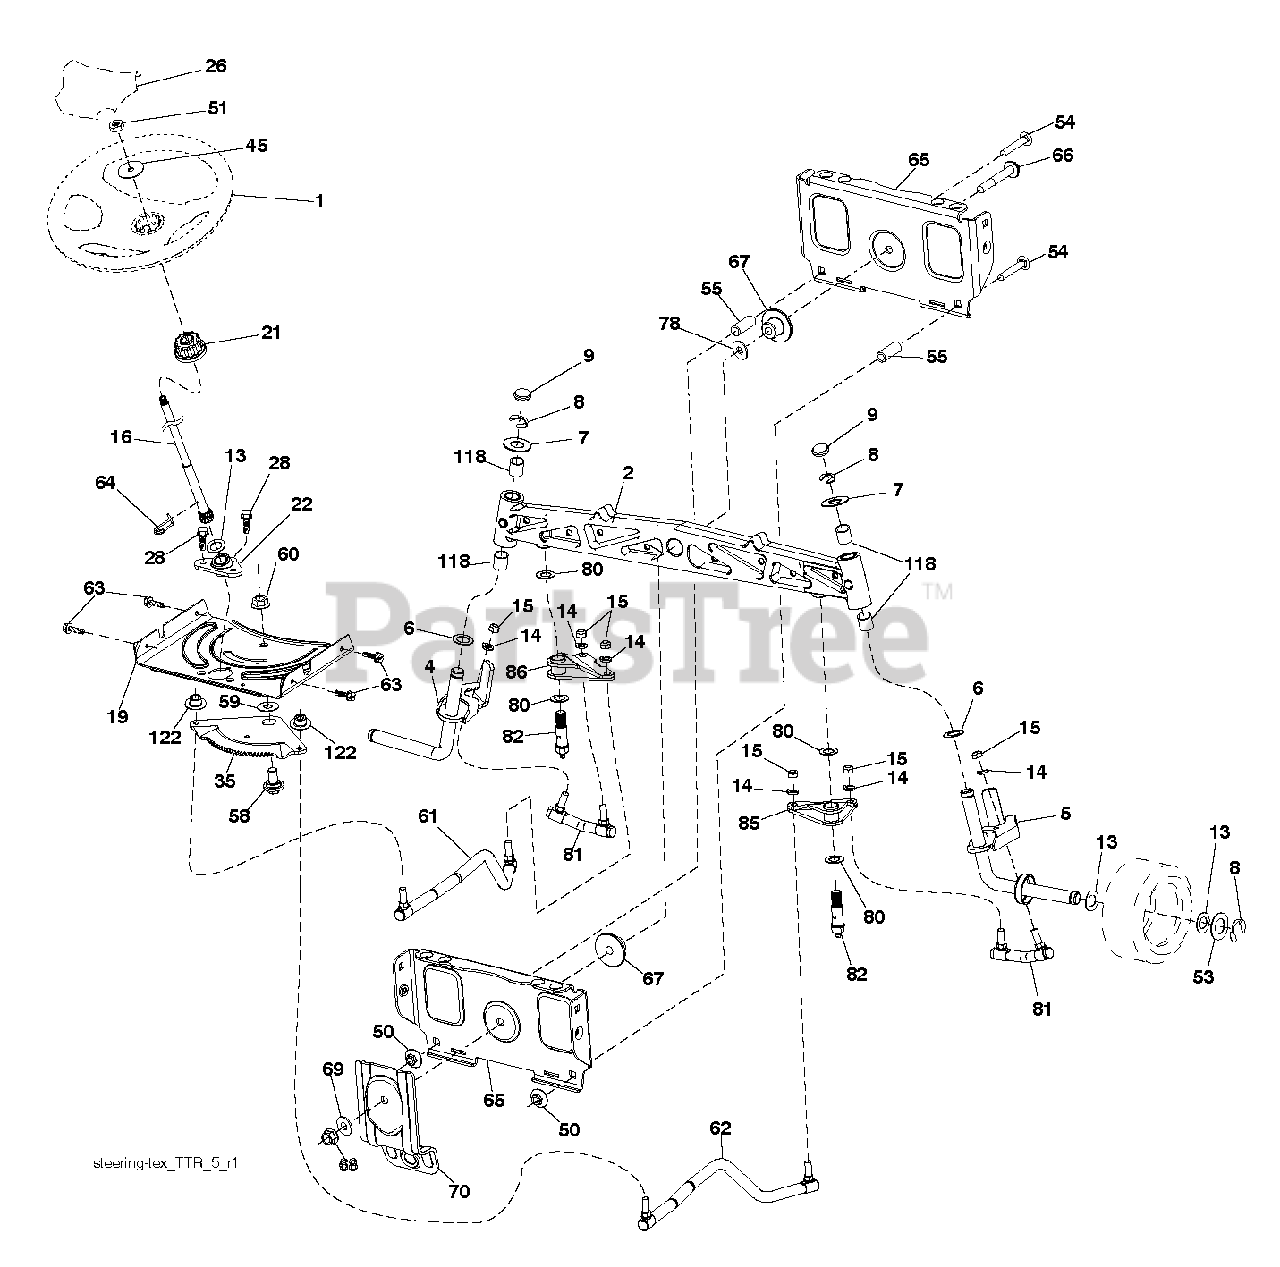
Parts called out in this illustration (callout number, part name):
1	WHEEL.STEER.HUSQ.SR.498.OVMLD
2	RP SUBASM.AXLE.CAST.NZTR.
4	SPINDLE WELDMENT.SPINDLE.LH.15
5	SPINDLE WELDMENT.SPINDLE.RH.15
6	THRUST WASHER
9	CAP.SPINDLE.BLACK
14	WASHER, LOCK 3/8
15	NUT CROWNLOCK 3/8-24
16	SHAFT SHAFT.STEERING.2HIGH.PLA
19	PLATE.STEER.DDL.NLT/NG
21	RP STEERING.WHEEL.ADAPTER
22	BUSHING.ASM.STEERING.A
26	INSERT.CAP.WHL.STRG.HUSQ.PREM
28	SCREW, 3/8-16X3/4
35	GEAR GEAR.SECTOR.TEX.NZTR
45	WASHER 9/16"ID, 2 3/8"OD
50	NUT LOCK FLG 3/8-16 UNC
51	NUT.HEX.1/2-20
53	WASHER.HARDENED
55	SPACER.BRACE.AXLE
58	BOLT.SHOULDER.SECTOR.P
59	WASHER.THURST.SECTOR.S
60	NUT FLANGE LOCK 5/8-11
61	LINK SUBASM.LINK.DRAG.LH.NZTR
62	TUBE TUBE
63	SCREW
64	RETAINER.CLIP.SPRING.S
65	BRACE.AXLE.FRONT.NLT/N
66	BOLT HEX FGHD 7/16-14 X 3 SERR
67	BUSHING.PM.FRONT AXLE
68	NUT.LOCK.FLANGE.7/16
69	WASHER.1.5X.505X.118
70	BRKT.DECK.SUSPENSION.F
78	THRUST WASHER
80	THRUST WASHER
81	LINK SUBASM.LINK.CROSS.NZTR
85	PIVOT SUBASM.PIVOT.RH.NZTR
86	PIVOT SUBASM.PIVOT.LH.NZTR
118	BUSHING, AXLE CAST
122	CAP.GEAR.SECTOR.TEX
